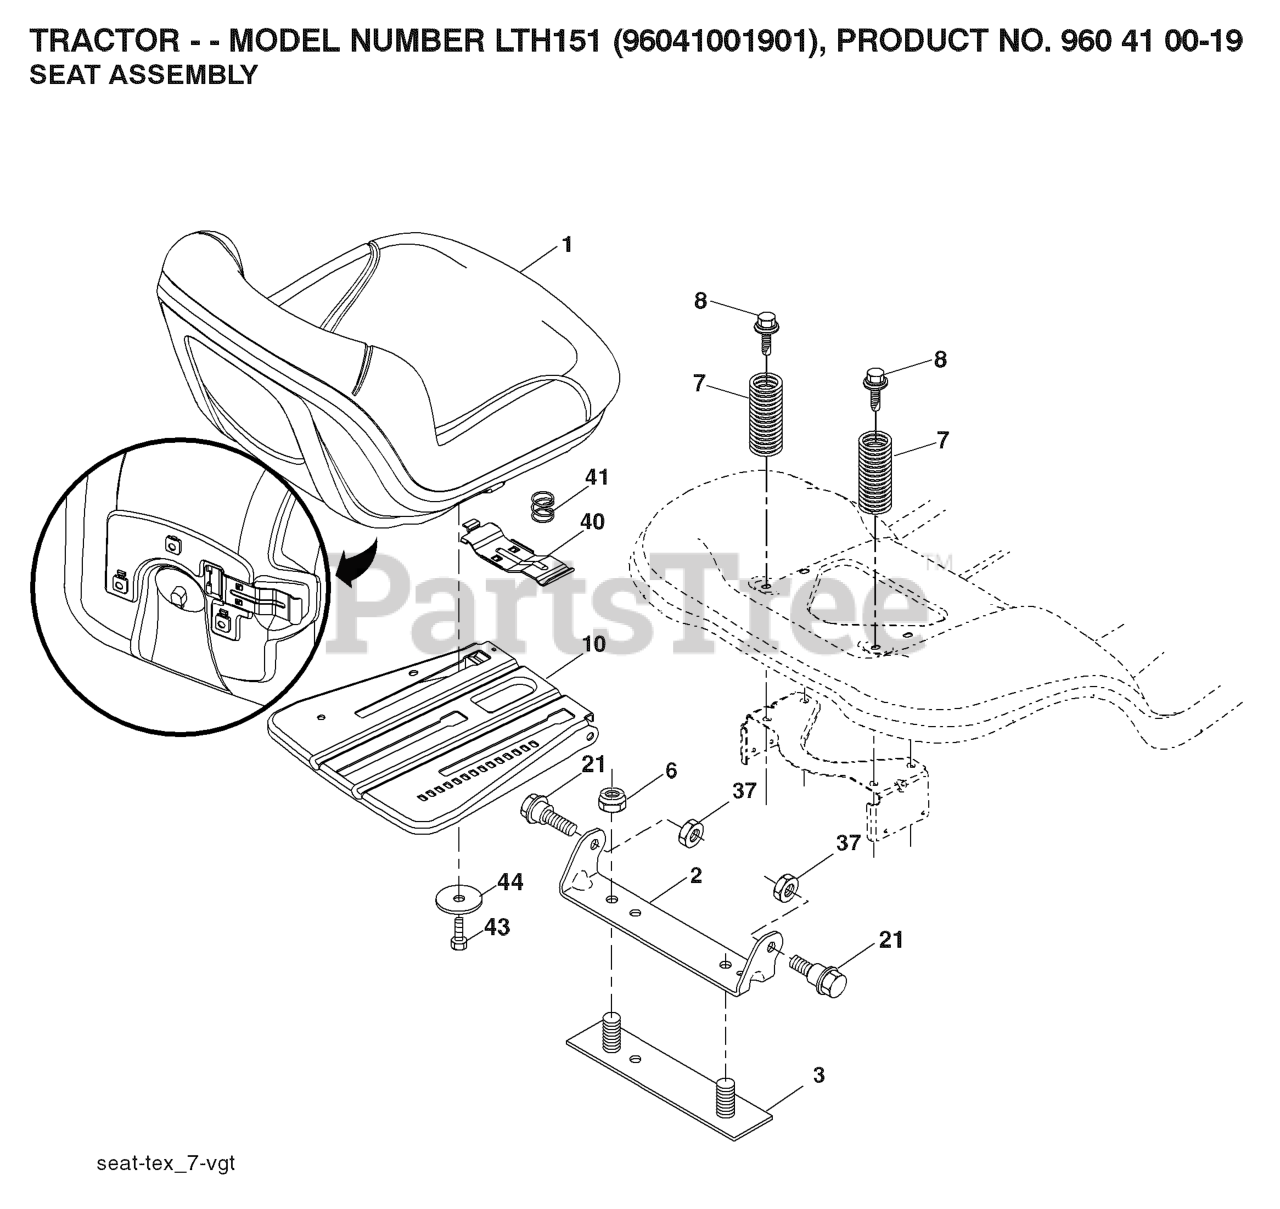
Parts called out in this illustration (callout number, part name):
1	SEAT.TH130.GRY.MILSCO.
2	BRKT.PIVOT.FENDER
3	STRAP
6	NUT
7	SPRING COMPRESSION
8	BOLT.5/16-18UNCX3/4 W/SEMS.BLK
10	PAN.ASM.SEAT.3PT
21	BOLT.SHOULDER.5/16-18
37	NUT.71038.31-18.HEX.NYLOCK
40	HANDLE.SLIDE.SEAT.TEX.BLACK
41	SPRING.LATCH.SEAT.TEX
44	WASHER 13/32 X 2-3/8 X 12GA
